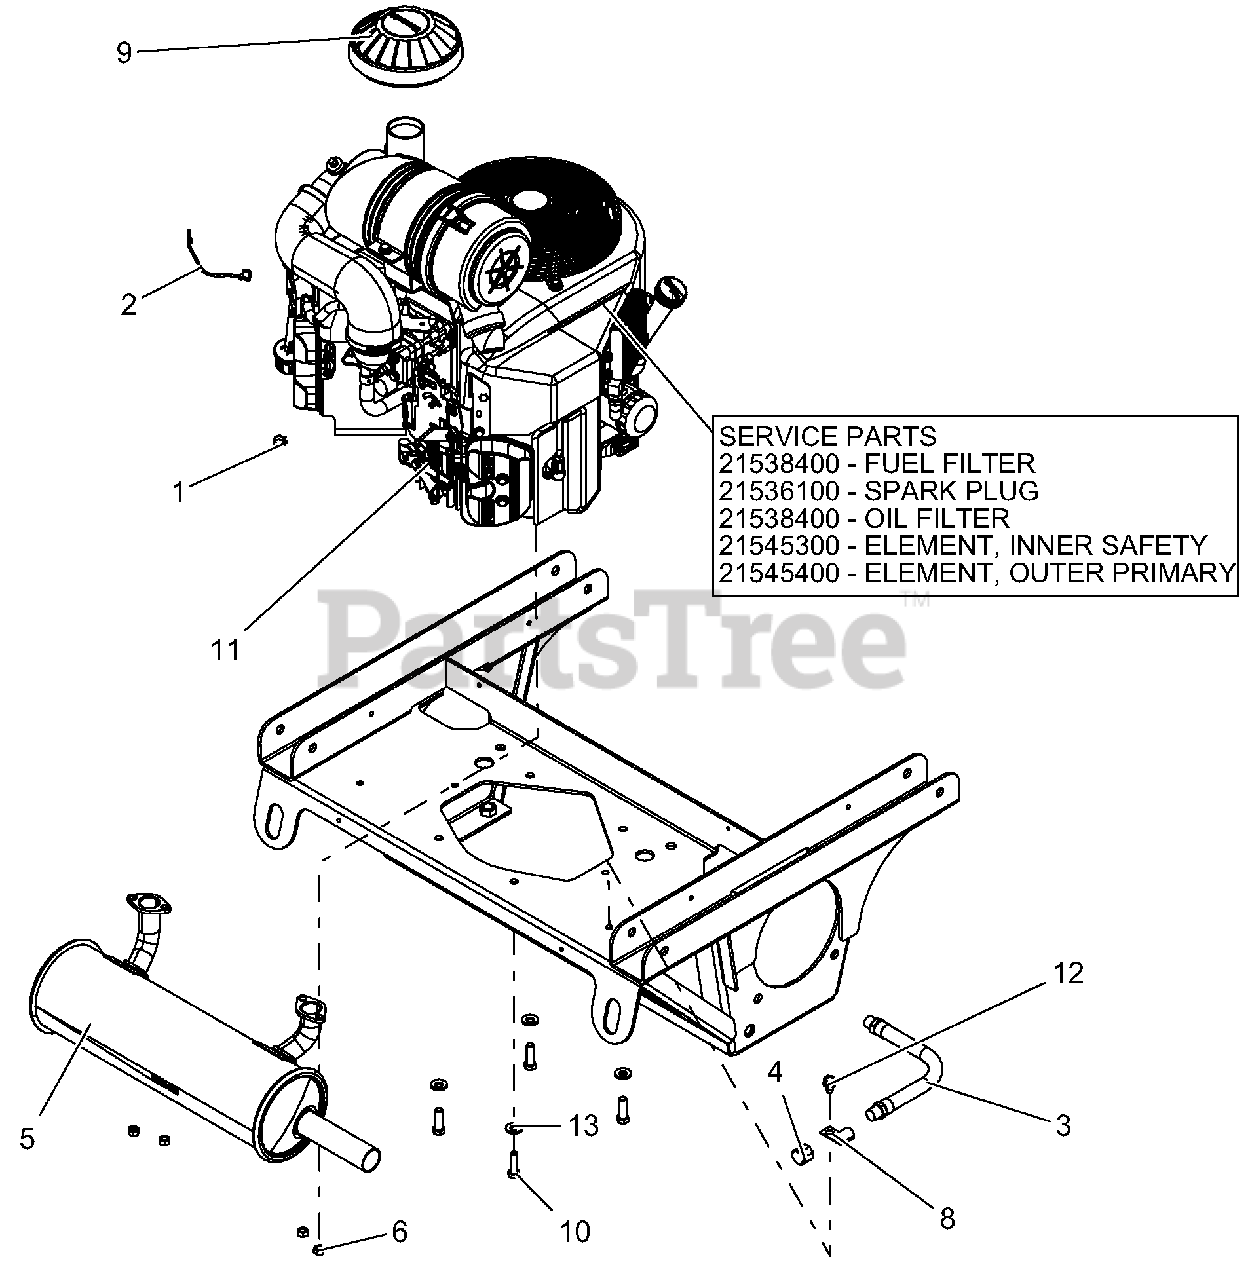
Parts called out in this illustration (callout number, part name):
1	CLAMP, FUEL LINE
2	LEAD - STARTER SOLENOID
3	HOSE, HYD .38-11-0K M6N0-M6NO
4	PIPE, CAP 3/8 NPT FEMALE
5	MUFFLER, 27-31 FX KAW
6	NUT-LK-TOP M8-1.25 YWZC
9	CAP, AIR CLEANER INTAKE (2")
10	BLT-HEX .38-16X1.25 GR5 YWZC NYTORQ
11	ENGINE, KAWASAKI FX751
12	SCR-TAP .38-16X.50 HWH TR YWZ
13	WSHR, 3/8" SPRING DISC
